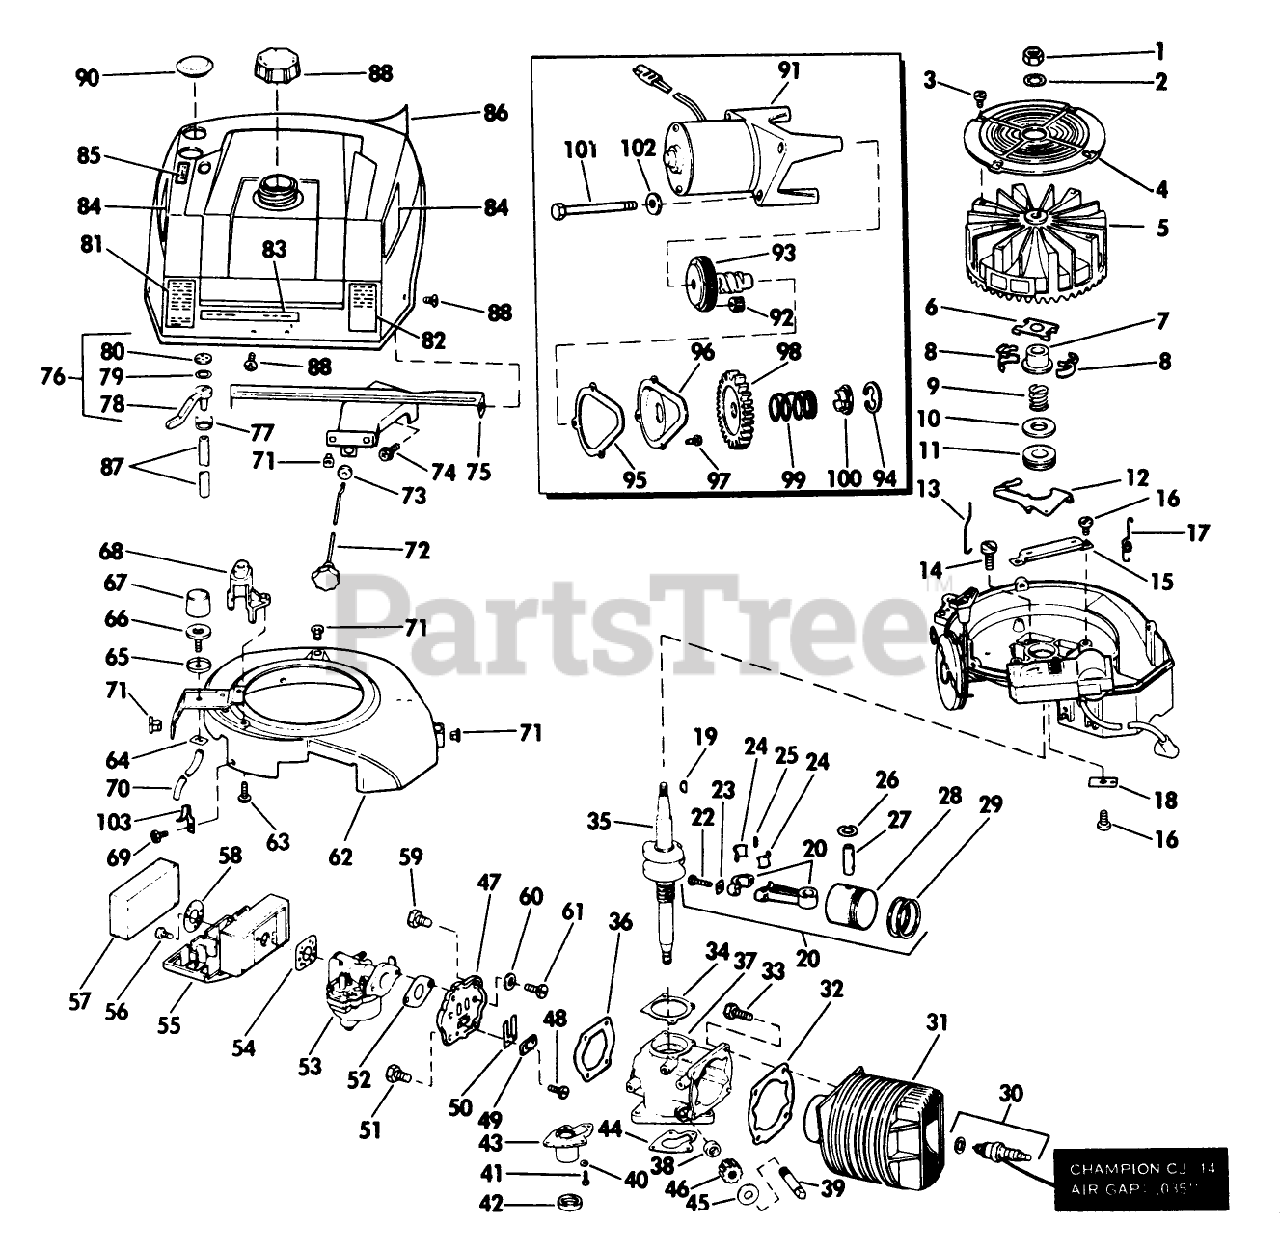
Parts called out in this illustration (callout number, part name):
3	SCREW F
7	COLLAR S
9	SPRING S
12	LEVER-GOVERNOR S
15	BRACKET
16	SCREW S
24	LINER ASM
26	RING-RETAINING
30	Spark Plug
32	GASKET S
34	GASKET S
36	GASKET S
43	GEAR COVER S
44	GASKET-CVR S
45	THRUST WASHER
46	GEAR, DR SHAFT S
47	REED PLATE AY. S
49	PLATE-BACKUP, REED
51	SCREW S
52	GASKET S
54	GASKET S
56	SCREW S
57	AIR FILTER S
58	WASHER S
59	SCREW S
64	LOCKNUT S
65	CUP-BULB
71	NUT-CLIP
74	SCREW S
75	BRACKET
79	WASHER S
88	SCREW S
94	RET.RING EF
